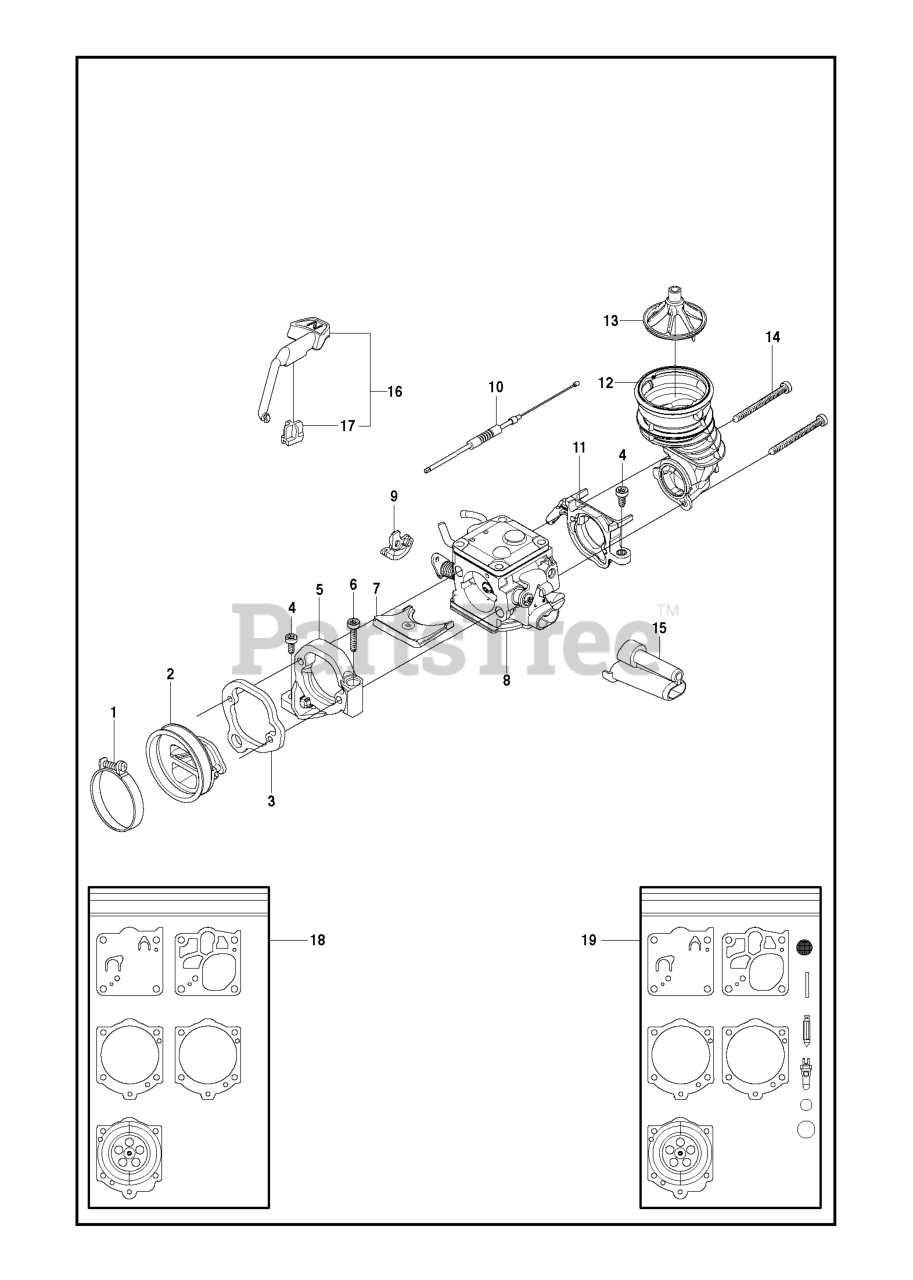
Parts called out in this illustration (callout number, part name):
1	HOSE CLAMP
2	INLET PIPE
8	CARBURETOR
9	LEVER OUTER
10	THROTTLE CABLE ASSY
11	FLANGE INLET PIPE
12	INLET PIPE
13	FILTER CONNECTION
14	SCREW
15	CHISEL GUIDE CARBURETOR K970 I
16	CHOKE CONTROL
18	GASKET KIT
19	REPAIR KIT CARBURETTOR
